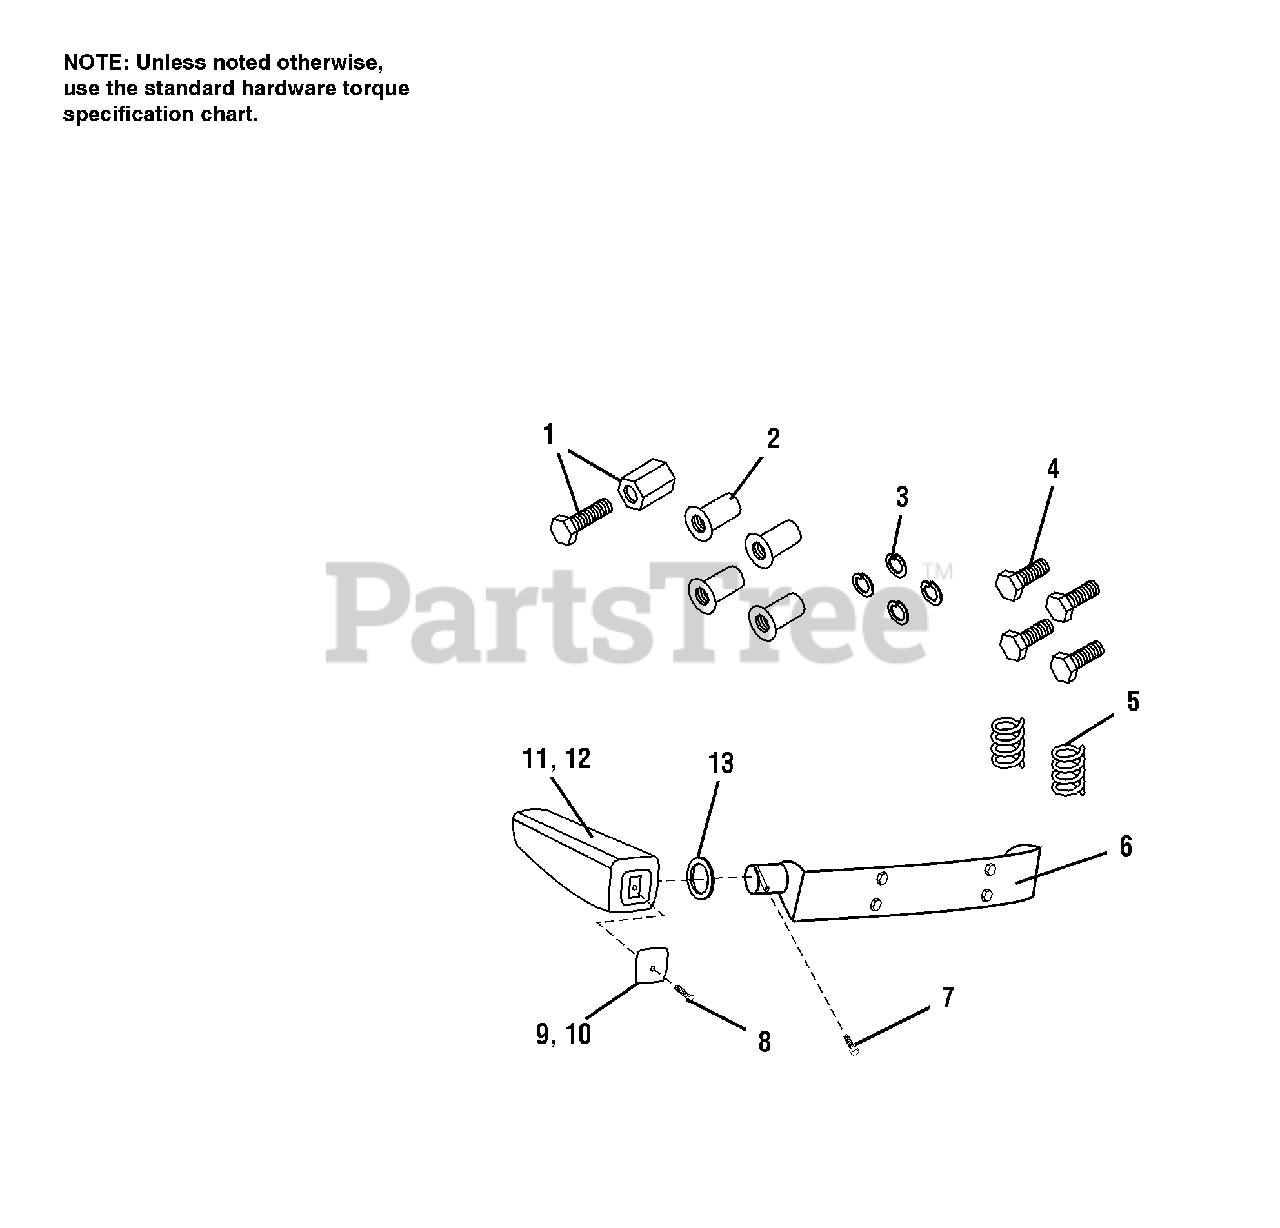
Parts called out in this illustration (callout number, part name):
1	INSERT TOOL
2	INSERT-NUT, Open End
3	LOCKWASHER, 3/8
4	BOLT, 3/8-16 x 3/4
5	SPRING, Compression
6	BRACKET, Arm Rest Mounting
7	ARM REST STOP
9	PLATE, Cover, LH
10	PLATE, Cover, RH
11	ARM REST, LH
12	ARM REST, RH
13	WAVE WASHER
